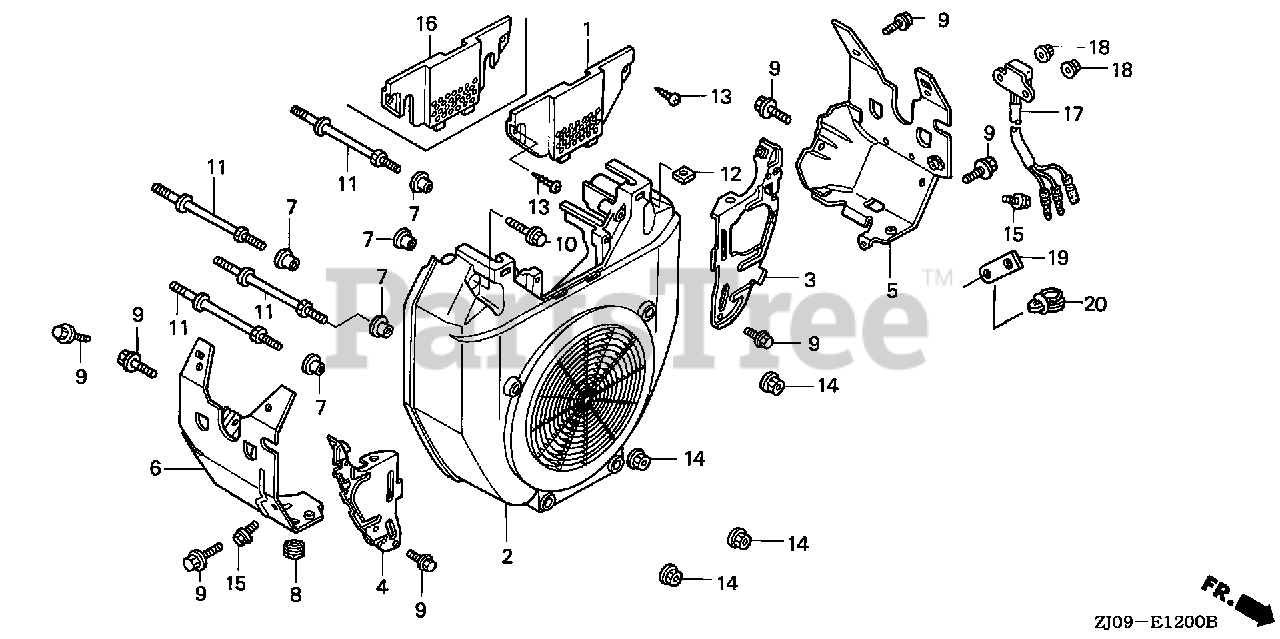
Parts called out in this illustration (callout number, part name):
2	COVER, FAN *NH1* (BLACK)
2	COVER, FAN *R8* (BRIGHT RED)
3	PLATE, R. SIDE
4	PLATE, L. SIDE
5	SHROUD, R.
6	SHROUD, L.
7	COLLAR B, TAILLIGHT
8	RUBBER, RR. FENDER CUSHION
9	BOLT, FLANGE (6X12) (CT200)
10	BOLT, FLANGE (6X23)
11	BOLT, STUD (6X71)
12	NUT, SQUARE (5MM)
13	SCREW, TAPPING (5X20)
14	NUT, FLANGE (6MM)
15	BOLT, FLANGE (6X8)
16	COVER, FUEL PUMP (MANUAL CONTROL)
